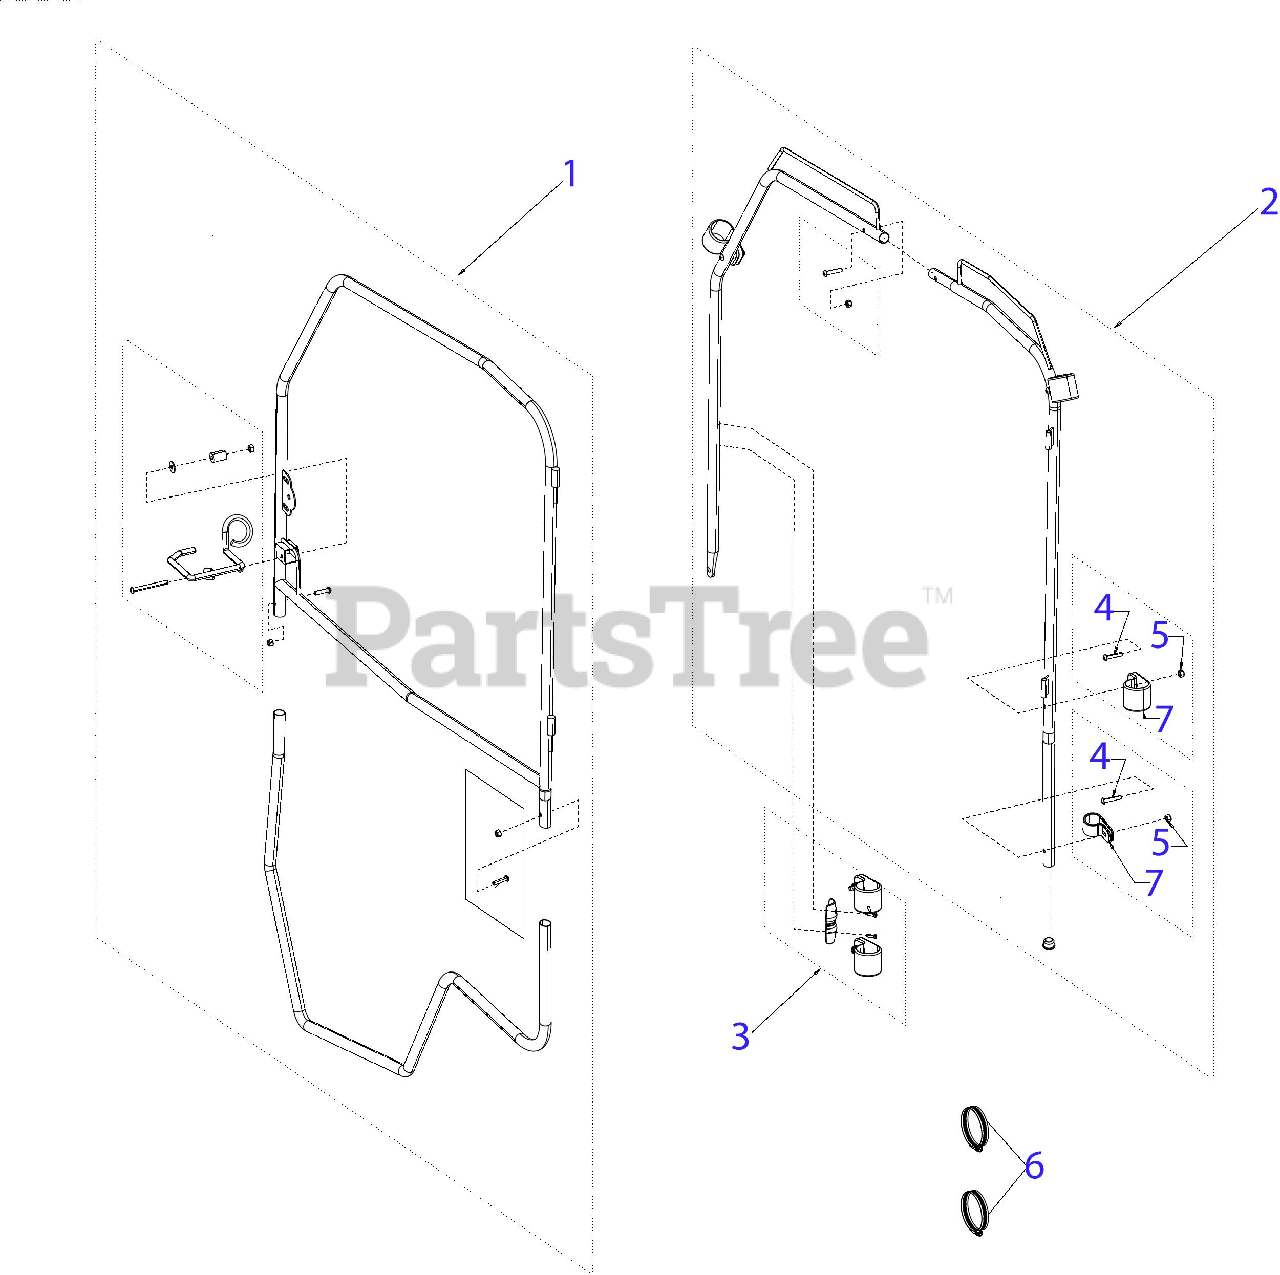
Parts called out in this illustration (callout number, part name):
1	Outer Frame Assembly - Driver
1	Outer Frame Assembly - Passenger
2	Inner Frame Assembly - Driver
2	Inner Frame Assembly - Passenger
3	LATCH LOCK ASSEMBLY
4	SCREW 1/4-20 X1.00 GR5
5	FLANGE LOCK NUT
6	HOSE CLAMP 2-3"
